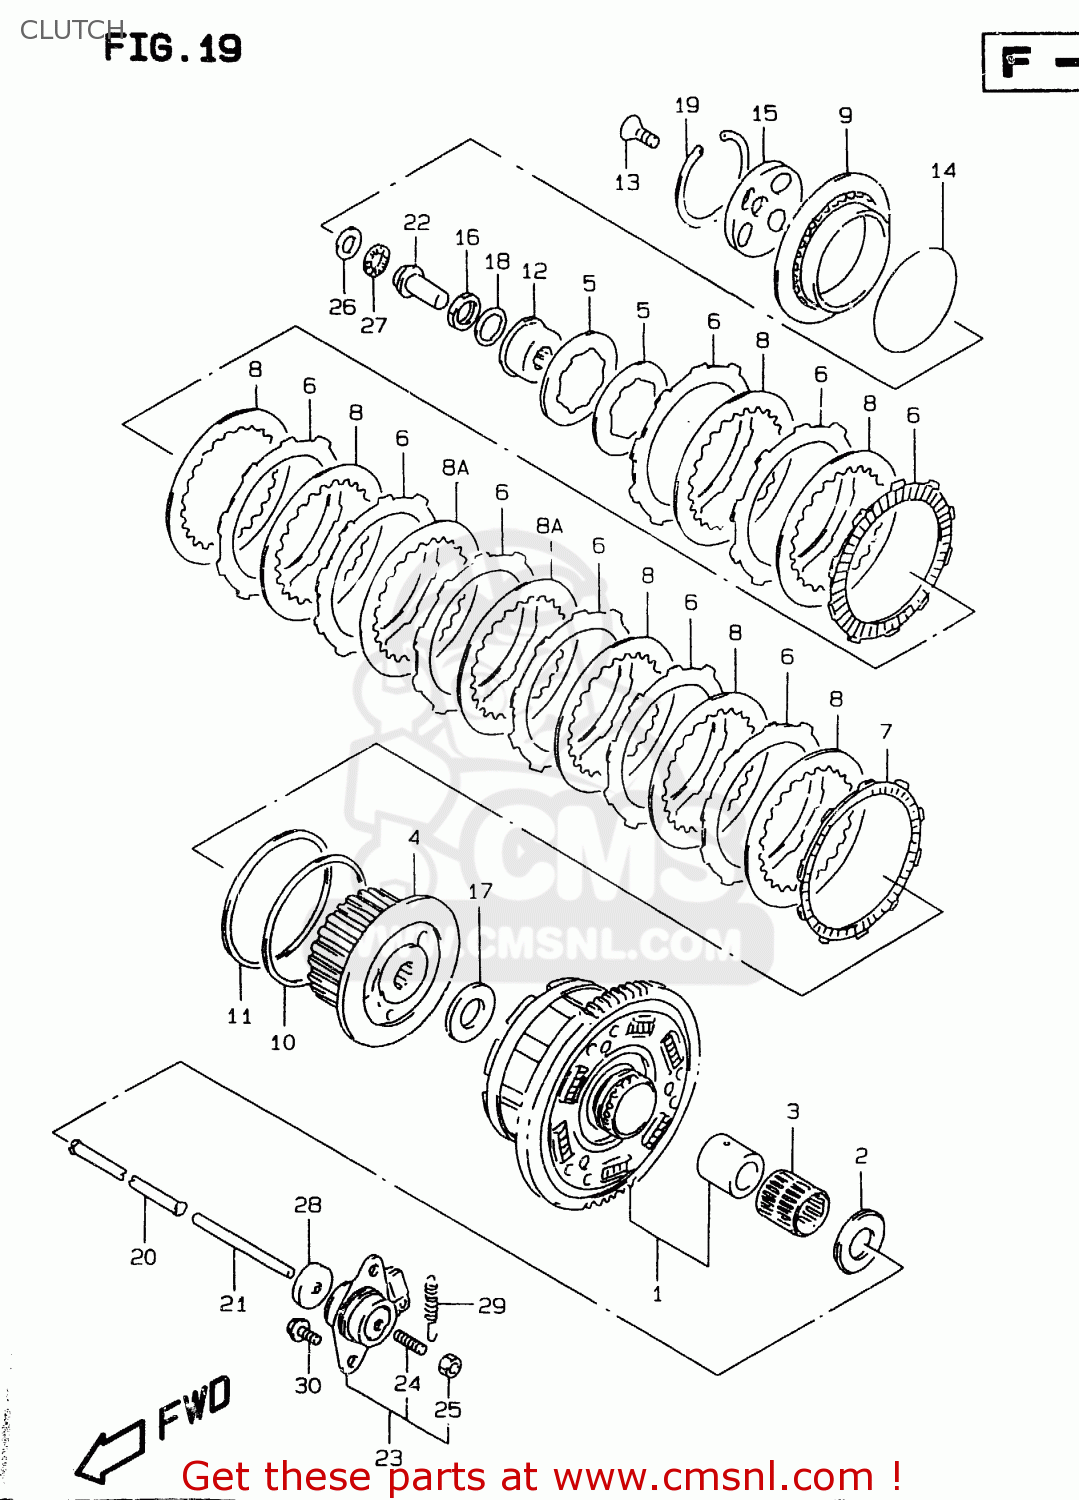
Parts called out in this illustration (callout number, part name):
1	GEAR ASSY,PRI DRIVEN
2	WASHER(25X54X2.5)
3	BEARING(35X40X35.8)
4	HUB,CLUTCH SLEEVE
5	SPRING,CLUTCH
6	PLATE,CLUTCH DRIVE
7	PLATE,CLUTCH DRIVE
8	PLATE,CLUTCH DRIVEN NO.1
8A	PLATE,CLUTCH DRIVEN NO.2
9	DISC,CLUTCH PRESSURE
10	SEAT,CLUTCH PLATE WAVE WASHER
11	WASHER,CLUTCH PLATE WAVE
12	HOLDER,CLUTCH SPRING
13	SCREW,CLUTCH SPRING HOLDER
14	SEAT,CLUTCH SPRING
15	LIFTER,CLUTCH PRESSURE DISC
16	NUT
17	WASHER
18	WASHER
19	CIRCLIP
20	ROD,CLUTCH
21	ROD,CLUTCH PUSH,L
22	PIECE,CLUTCH PUSH
23	SCREW ASSY,CLUTCH RELEASE
24	SCREW(6X25)
25	NUT
26	WASHER(15.5X28X1)
27	BEARING(15X28X2)
28	SEAL,OIL(6X34X5.5)
29	SPRING
30	BOLT
